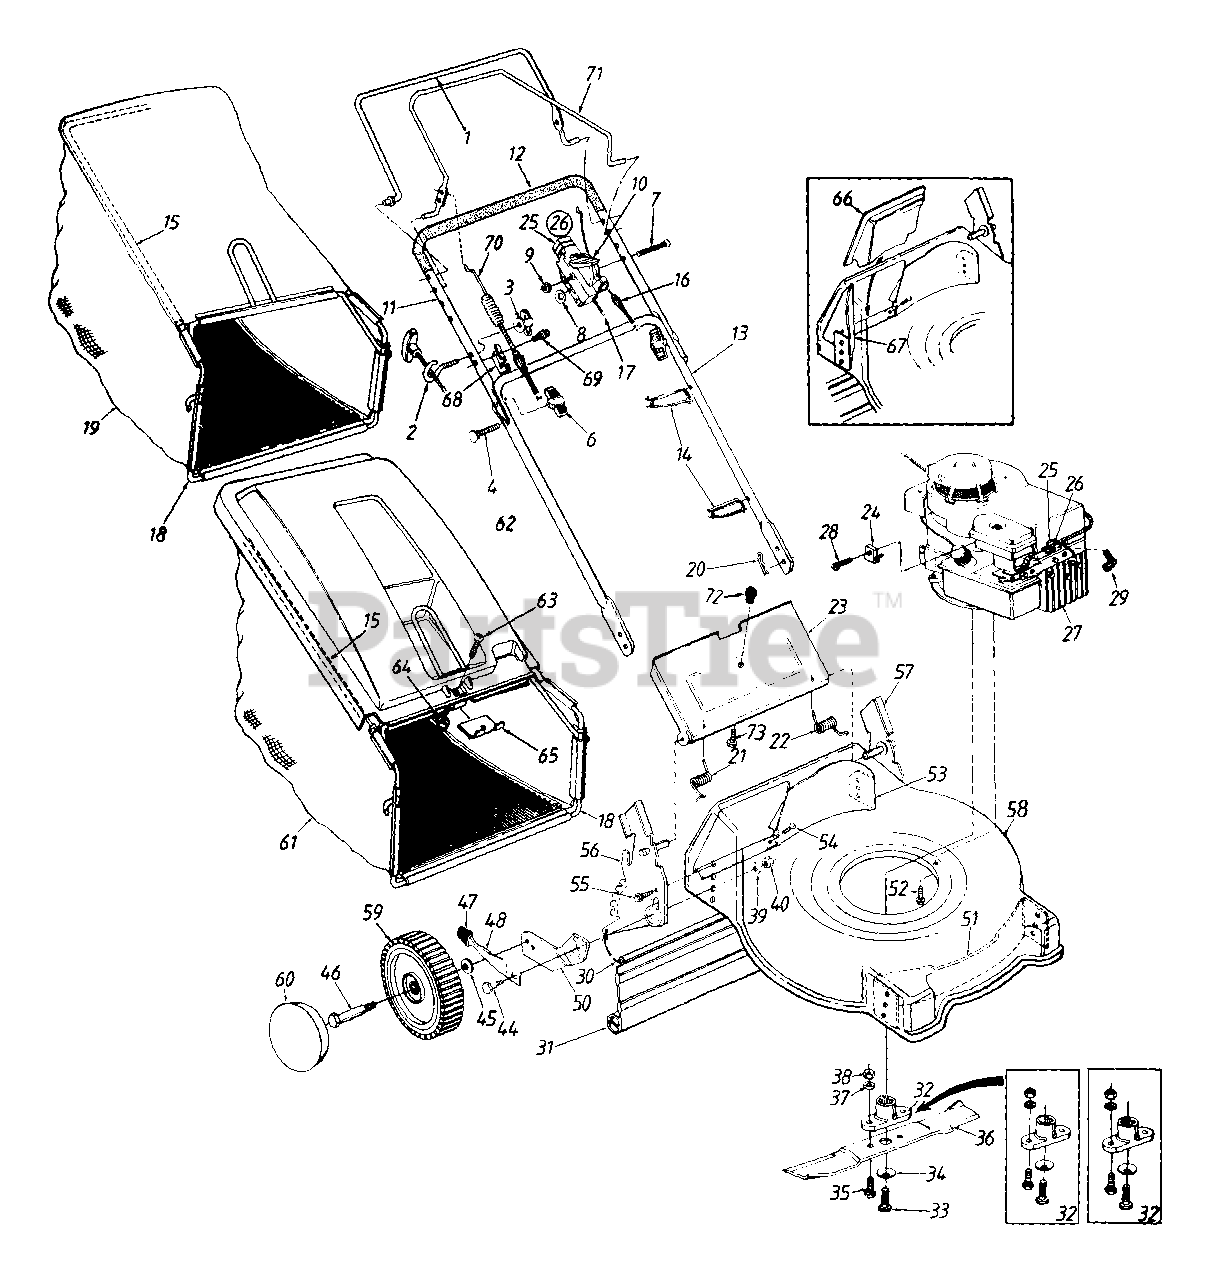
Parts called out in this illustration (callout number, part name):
2	Rope Guide
3	Wing Nut 1/4-20 Thd
4	Curved Hd. Bolt 5/16-18 x 2" Lg.
6	Hand Knob
7	Oval C-Sunk Mach. Scr.
8	Spr Wash. 66" I.D.
9	Hex L-Nut 1/4-20 Thd.
10	Throttle Lever
14	Cable Tie
16	Control Cable - 39"
17	Throttle Control Wire - 51"
20	Int. Cotter Pin 5/16" Dia.
21	Door Spring - R.H.
22	Door Spring - L.H.
25	Throttle Body
26	Throttle Box Comp.
27	Engine
28	Hex Wash. Hd. Scr. #10-32 x 62" Lg.
29	Spark Plug Boot
30	Wire Rod
31	Rear Flap
32	Blade Adapter Kit
33	Hex Bolt 3/8-24 x 1.5" Lg.
34	Bell-Wash..39" I.D.
35	Hex Bolt 3/8-24 x 1" Lg.
36	21" Blade
37	L-Wash. 3/8" I.D.
38	Hex Nut 3/8-24 Thd
39	Bell-Wash 39" I.D. x 1.38"
40	Hex Nut 3/8-16 Thd
44	Shld Bolt 5" Dia. x .357"
45	Bell-Wash .38" I.D. x .88" O.D.
46	Axle Bolt
47	Spring Lever Knob
48	Spring Lever
50	Pivot Bar
54	Torx Mach AB-Tap Scr 1/4 x .62" Lg.
55	Hex L-Wash Hd AB-Tap Scr 1/4 x 62" Lg.
56	Handle Brkt Ass'y - R.H.
57	Handle Brkt. Ass'y - L.H.
60	Hub Cap
61	Grass Bag
62	Hard Top Cover
63	Pan Hd Mach Scr 1/4-20 x 5" Lg.
64	Hex Nylon L-Nut 1/4-20 Thd.
68	Cable Mtg. Brkt.
69	Hex Wash. AB-Tap Scr 5/16" x .75" Lg.
70	S.P Cable 44.75" Lg.
73	Truss Mach Scr #10-24 x .38" Lg.
